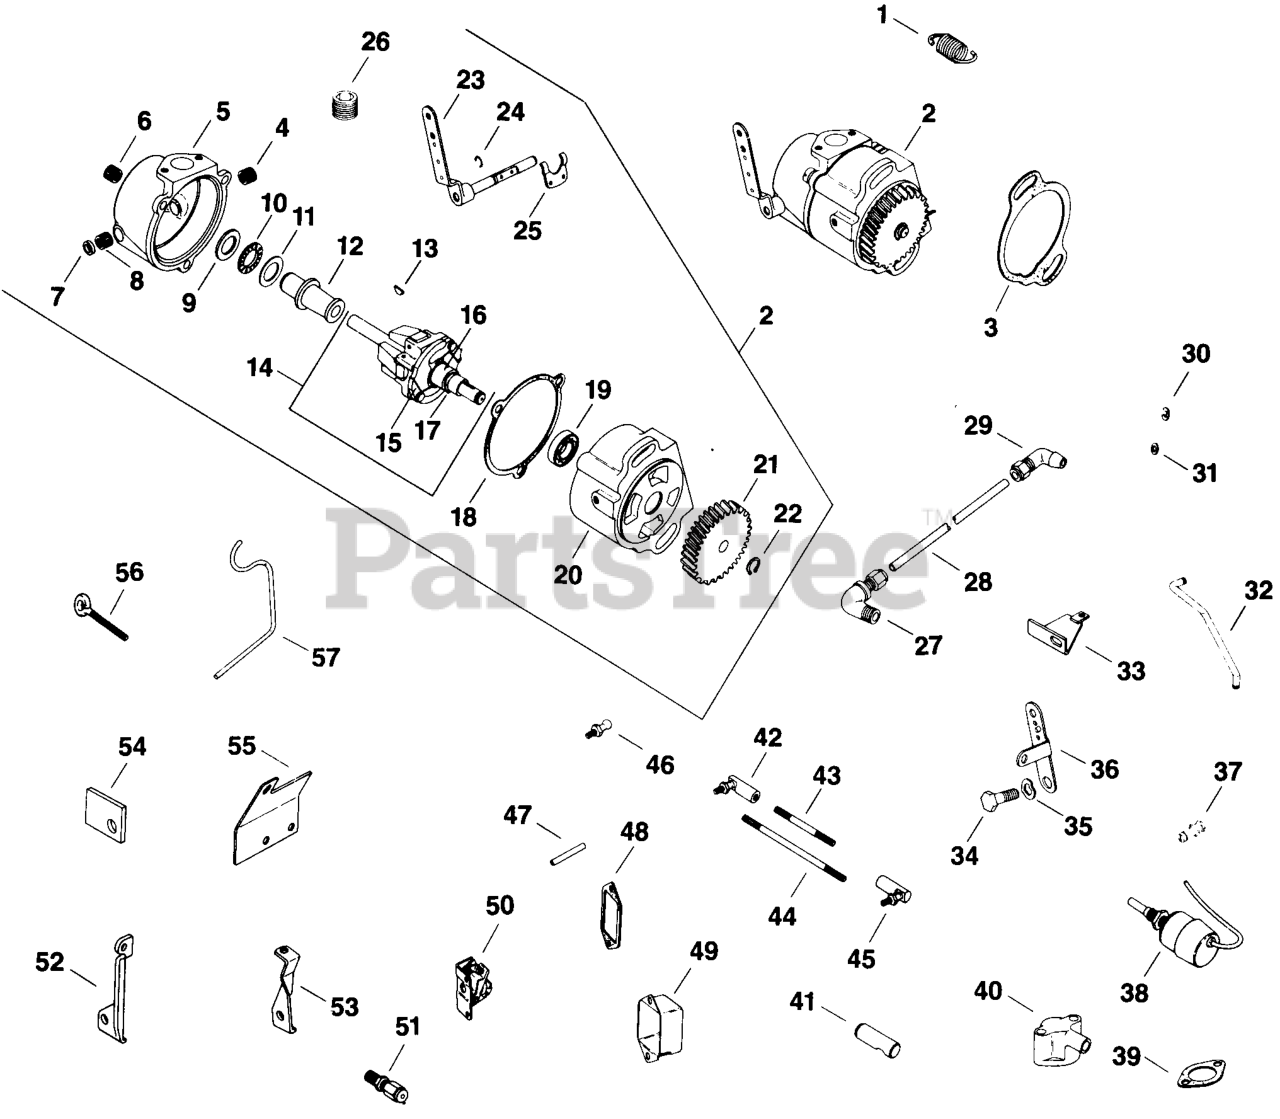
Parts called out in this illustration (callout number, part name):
1	SPRING - DISCONTINUED
2	KIT, GOVERNOR - DISCONTINUED
5	COVER - DISCONTINUED
7	SEAL - (#DSC)
10	BEARING - DISCONTINUED
12	KIT, THRUST SLEEVE
13	KEY, 3/32" X 3/8"
14	SHAFT - (#DSC)
15	SPRING - DISCONTINUED
16	CAM - (#DSC)
18	GASKET - DISCONTINUED
19	BEARING - (#DSC)
21	GEAR - DISCONTINUED
26	PLUG, CTSK PIPE 1/8" USE 25 139 60-S
35	WASHER, SPRING 3/8"
36	LEVER - DISCONTINUED
40	BREATHER - DISCONTINUED
42	JOINT
43	STUD,#10-32X2-1/8"
45	JOINT
48	GASKET, POINT COVER
49	COVER - DISCONTINUED
